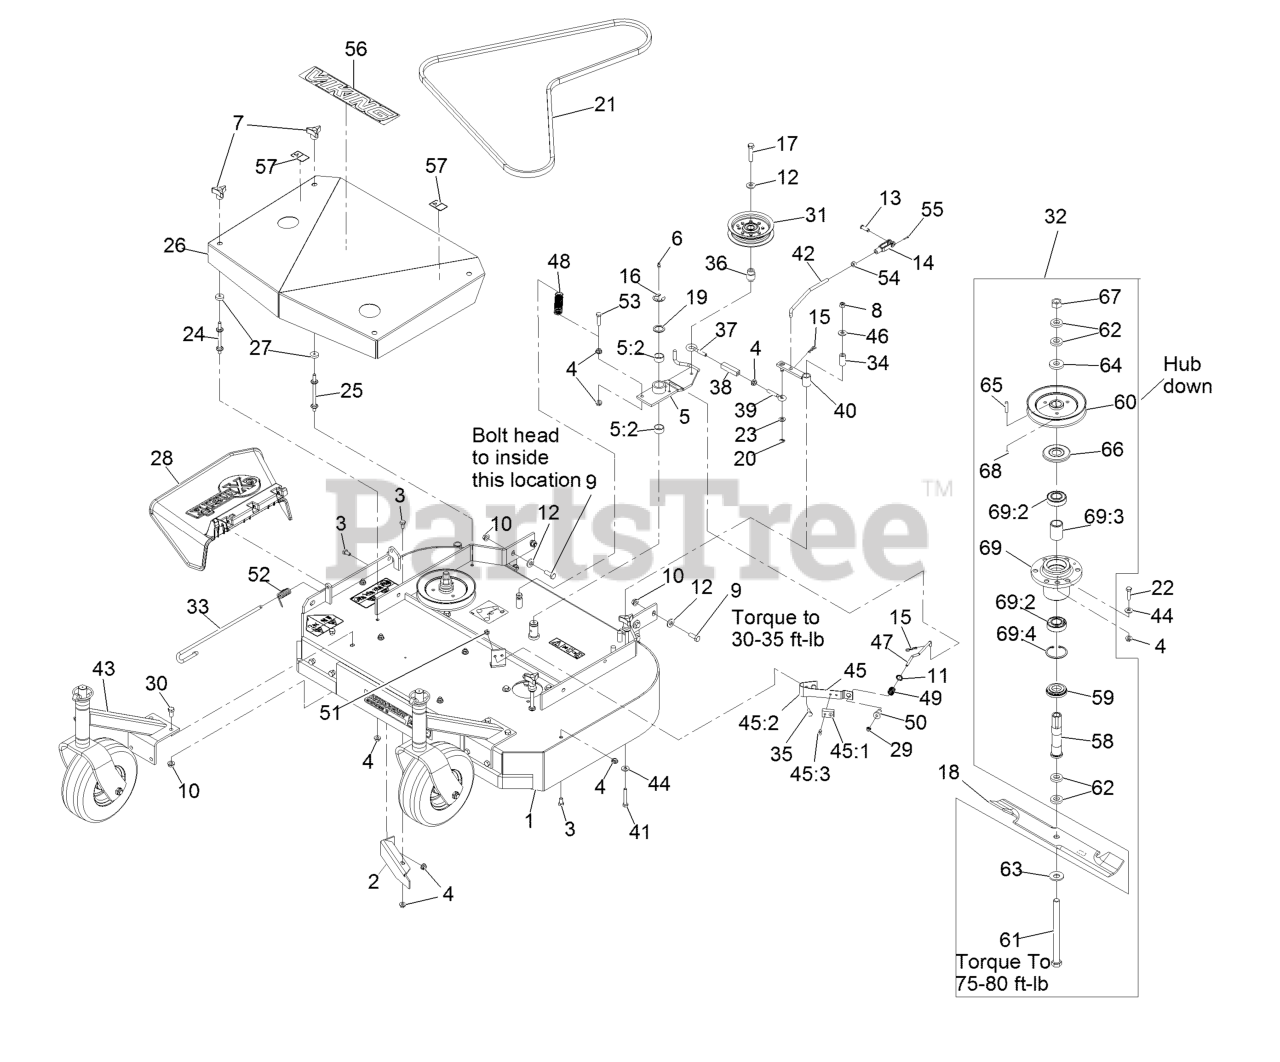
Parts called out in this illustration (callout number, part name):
1	Deck W/Decals And Dogleg
2	Baffle-Dogleg
3	Screw-HH 5/16-18 X 5/8
4	Nut-Whizlock 5/16-18
5	Idler Arm ASM
5:2	Sleeve-Bearing
6	Zerk-1/4-28 Str
7	Knob-3 Prong
8	Nut-Nyloc 5/16-18
9	Screw-HH 3/8-16 X 1
10	Nut-Whizlock 3/8-16
11	Ring-Push On
12	Washer-Spring Disc 3/8
13	Pin-Clevis 5/16 X 1 49/64
14	Yoke-Adjustable
15	Hairpin-Cotter
17	Screw-HH
18	Blade, Solid 18.00
18	Blade, 18.00 Low Lift
18	Blade, 18.00 Mulching
18	Blade, 18.00 Notched
18	Blade-Extreme 2, 18.00"
19	Washer-Spindle
21	Drive Belt (To Blades)
22	Screw-HH 5/16-18 X 1 1/4
23	Washer-5/16 SAE
24	Stud-Shield, Belt (Short)
25	Stud-Shield, Belt (Long)
26	ASM,Shield W/Decals 36 Viking
27	Washer-Belt Shield
28	Deflector-Discharge
29	Nut-Nyloc 1/4-20 Thin
30	Screw-HH 3/8-16 X 3/4
31	Pulley-Idler
32	Asm, Cutter Housing Complete
33	Pin-Chute
34	Tube-Pivot
35	Screw-HH 1/4-20 X 3/4
36	Bushing-Engagement
37	Eyebolt-Thread, LH
38	Body-Turnbuckle
39	Eyebolt-Thread, RH
40	Arm-Assist, 32/36
41	Screw-HH 5/16-18 X 2
42	Arm-Linkage, Assist
43	ASM-Caster Mnt W/Weight
44	Washer-Spring Disc 5/16
45	Pad And Spring ASM
45:1	Pad-Brake
45:2	Spring
45:3	Rivet 3/16 X 1/2
46	Washer-5/16 Std
47	Rod-Brake
48	Spring-Extension
49	Spring-Compression
50	Spacer-Flanged
51	Nut-Nyloc 1/4-20
52	Spring, Torsion
53	Screw,HH Special 5/16-18 X 1.25
54	Nut-Hex 5/16-24
55	Pin-Cotter 3/32 X 1/2
56	Decal, Viking Hydro Model
57	Decal-Warning
58	Tube-Spindle, Short
59	Spacer-Guard Bottom
61	Screw-Cap, HH
62	Spacer-Blade Drive
63	Washer-Spring Disc 5/8
65	Key-Machine 1/4 X 3/16 X 1 1/4
66	Guard-Bearing Top
67	Nut-Hex 5/8-18
68	Setscrew-5/16-18 X 3/8
69	Cutter Housing ASM
69	Asm, Cutter Housing W/Bearings
69:2	Bearing-Jackshaft
69:3	Spacer-Bearing
69:4	Ring-Retaining
